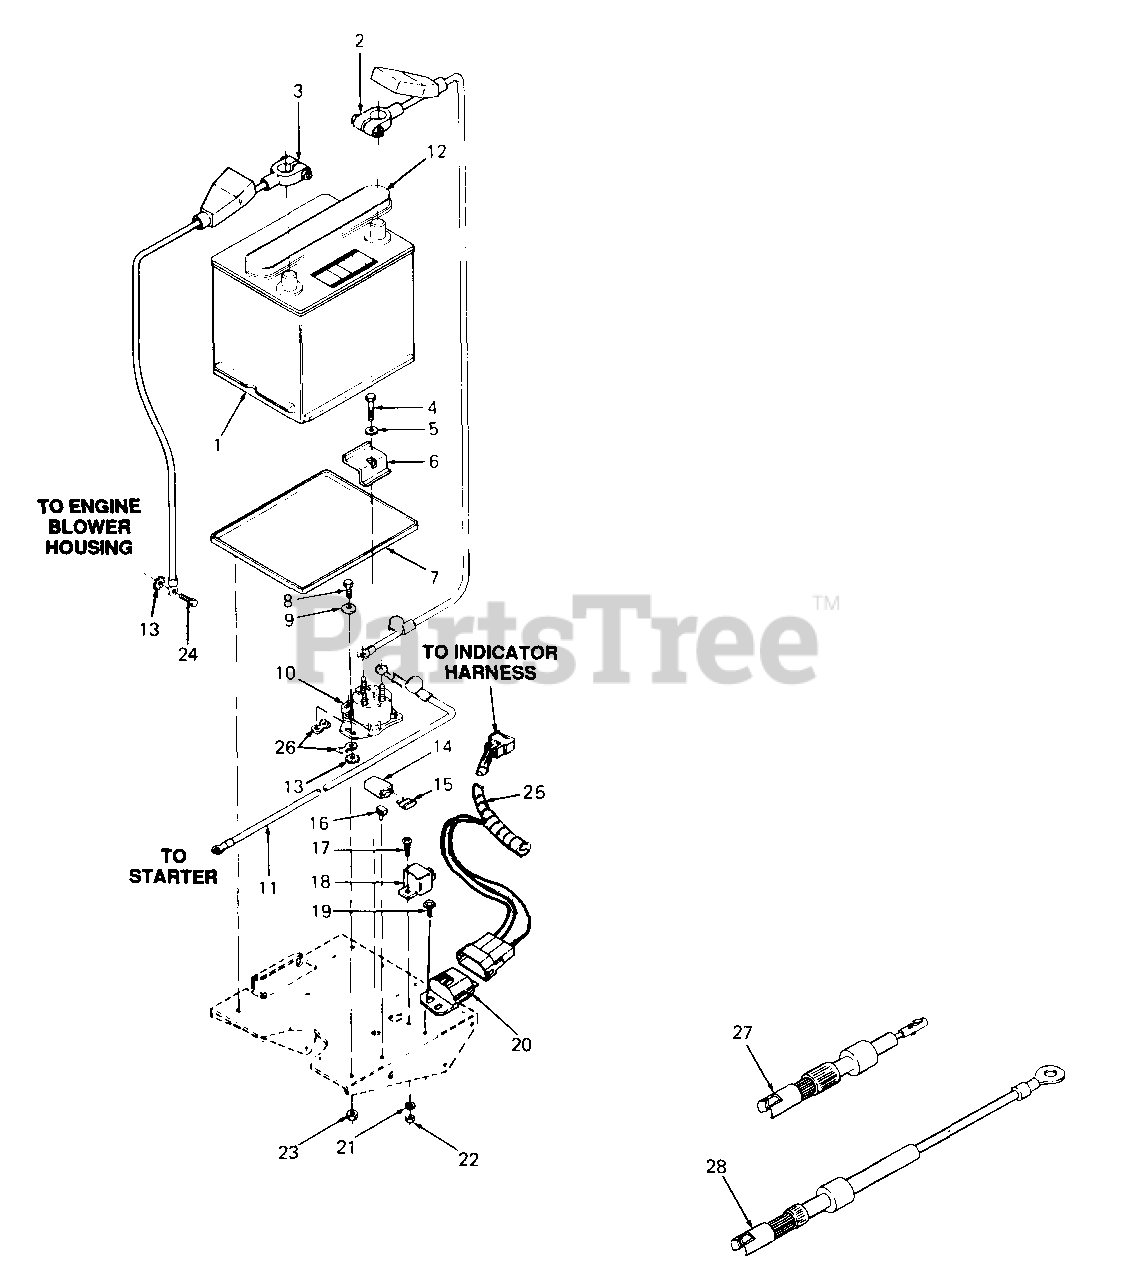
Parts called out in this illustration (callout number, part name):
1	Battery
2	Cable, Positive Battery
3	Cable, Negative Battery
4	Screw, Hex Cap, 5/16-18 X 1.38 Lg
5	Washer, Flat, .34 X .68 X .062 Thk
8	Screw, Hex Cap, 1/4-20 X .62 Lg GR5
9	Washer, Bell, .265 X .75 X .062 Thk
10	Solenoid
11	Cable, Starter
12	Cap, Battery Vent
13	Washer, Int-Ext, 1/4
14	Holder, Fuse
15	Fuse, 20 Amp
16	Clip, Fuse Holder Mtg
17	Screw, Truss Mach, #10-24 X .50 Lg
18	Relay
19	Screw, Hex Wash HD TT, 1/4-20 X .50 Lg
20	Module, Voltage Sensor
21	Washer, Lock, #10
22	Nut, Hex, #10-24
23	Nut, Hex Center Lock, 1/4-20
24	Screw, Sems
25	Main Harness
26	Lug, Quick Connect
27	Diode Assy
28	Diode Assy w/Lead
